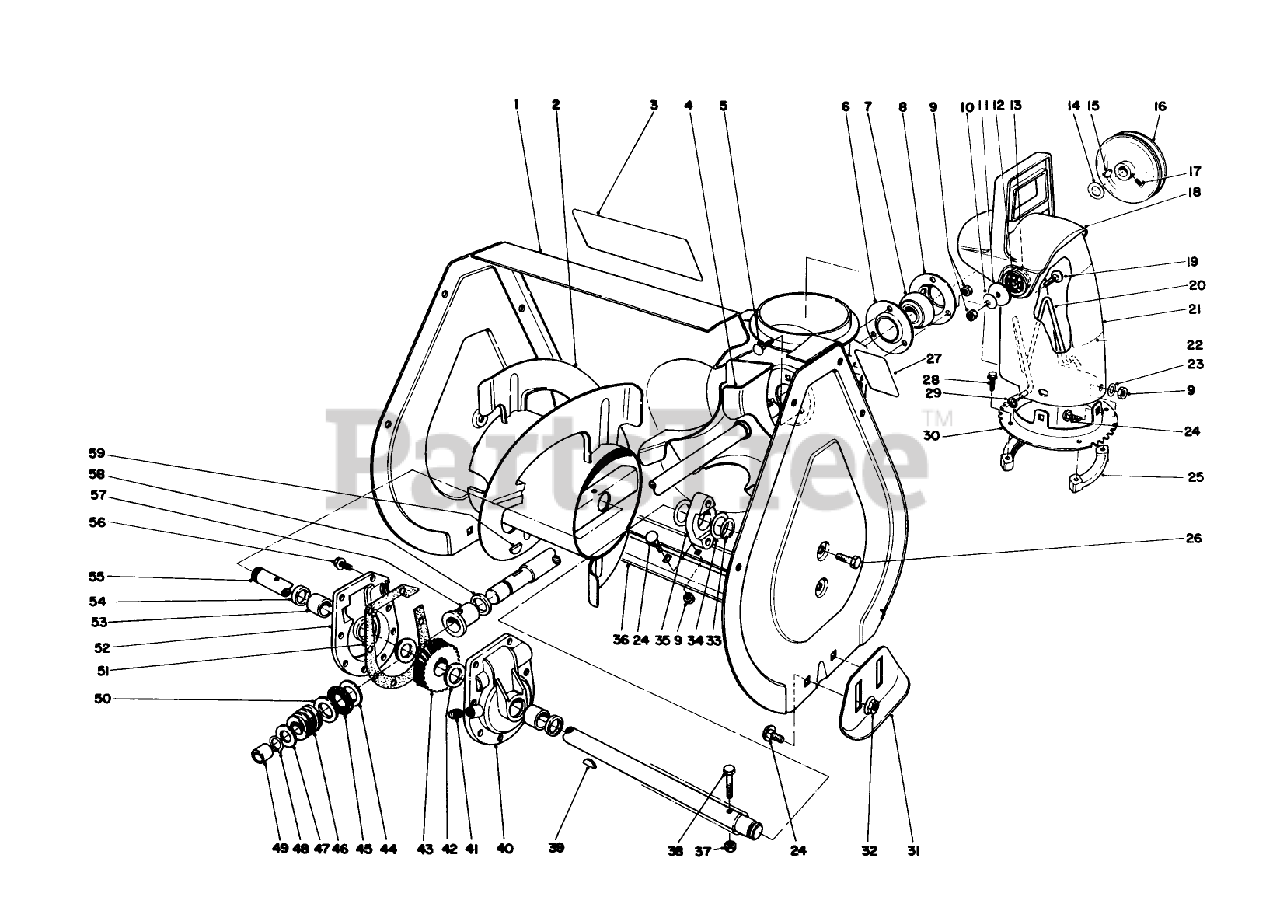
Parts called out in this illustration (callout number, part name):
1	Housing-Auger (Incl. Ref. #3 & 27)
2	Auger R.H.
3	AUGER WARNING DECAL
4	Shaft & Impeiler
5	BOLT-CARR
6	FLANGE-CUP, BEARING
7	Ball Bearing
8	FLANGE-CUP, BEARING
9	NUT-LOCK, NI
10	WASHER-BELLEVILLE
11	WASHER-FLAT
12	PLATE-FRICTION
13	WASHER-RUBBER
14	WASHER
15	KEY-WOODRUFF
16	PULLEY
17	SCREW-SET, SQH
18	CHUTE-DEFLECTOR
19	SCREW-CARR
20	WIRE-CHUTE
21	Chute-Discharge (Incl. Ref. #22)
22	Decal-Discharge
23	WASHER-PLAIN
24	BOLT-CARR
25	RING-CHUTE, RETAINER
26	SCREW-HWHTF
27	DECAL-WARNING, AUGER
28	SCREW-SPECIAL
29	NUT-PUSH
30	Chute Ring
31	Skid
32	NUT-HF
33	RING-RETAINING
34	WASHER
35	BEARING-AUGER
36	Blade-Scraper
37	NUT-LOCK, CONE
38	SCREW-HH
39	KEY-WOODRUFF
40	Gear Case-L.H. (Incl. Ref. #53 & 54)
41	PLUG-PIPE, SQH
42	WASHER-THRUST
43	Gear
44	WASHER-THRUST
45	BEARING-THRUST
47	WASHER-THRUST
48	Ring-Snap
49	BUSHING
50	WASHER-THRUST
51	GASKET-CASE, GEAR
52	Gear Case-R.H. (Incl. Ref. #53 & 54)
53	BUSHING
54	SEAL-OIL
55	AUGER SHAFT
56	SCREW-TAPTITE
57	BUSHING-INPUT
58	RING-QUAD
59	KEY-WOODRUFF
